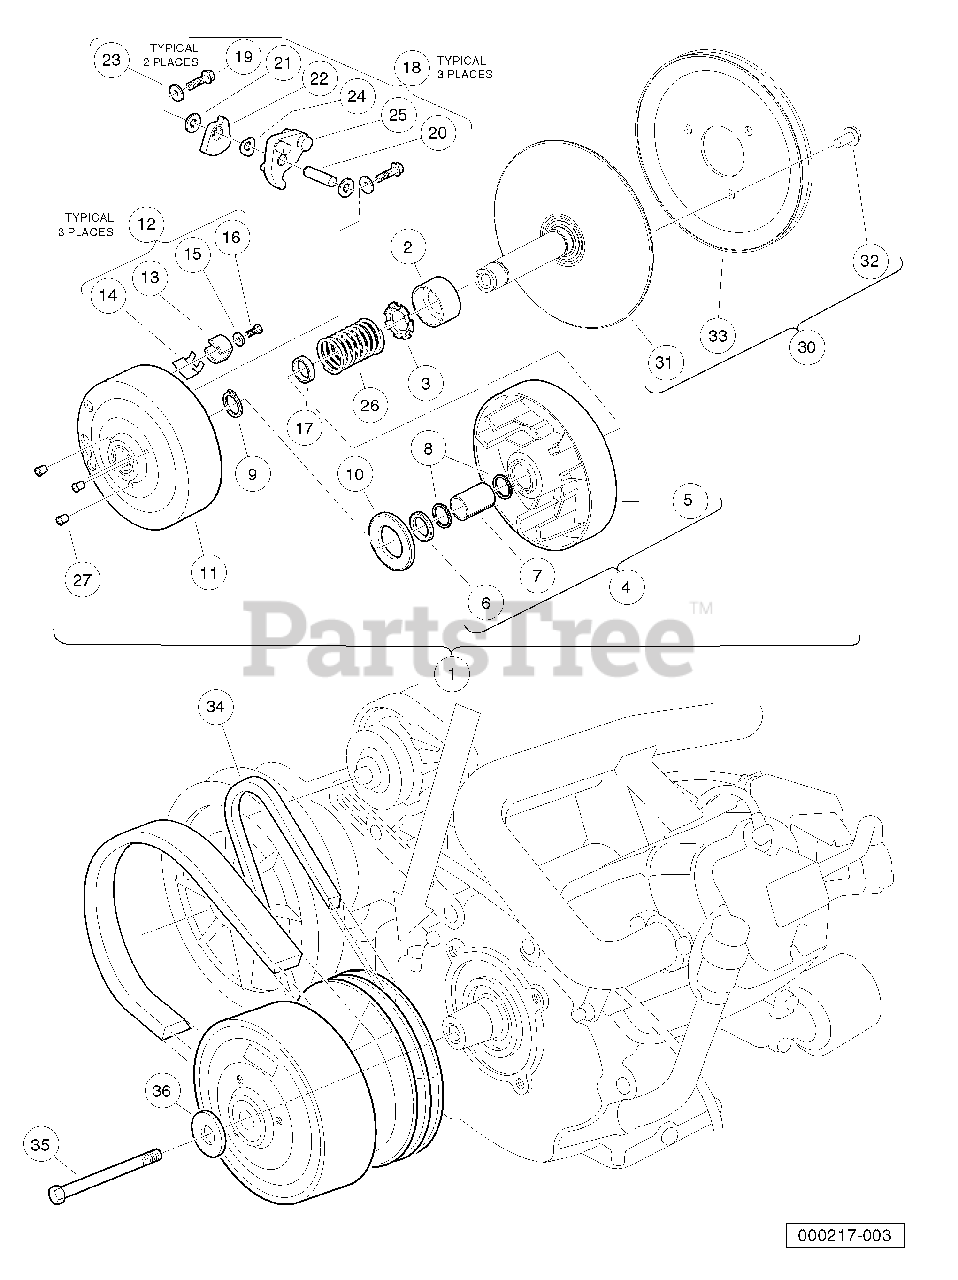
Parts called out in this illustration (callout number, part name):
1	Drive Clutch Assy. FE 350/272
2	Bearing, Idler
3	Retainer, Spring
4	Movable-Face Assembly
5	Drive Clutch Movable Face
7	Bushing, Split, Drive Clutch
8	Ring, Spiral Backup
9	Ring, 0.810" Internal Retaining
10	Washer, Thrust
11	Drive Hub Assy, Drive Clutch
12	Kit, Drive Clutch Button
13	Driver, Drive Clutch
14	Spring, Drive Button
15	Washer, #10 Type A Flat
16	Screw, #10-24 X 0.50 Hex-Head
17	Spacer, Fixed Face Shaft
18	Kit, Drive Clutch Weight
19	Screw, 1/4-20 X 1.00 Hex Head
20	Pin, 0.3752 X 1.50 Dowel
21	Washer, 0.38" ID Delrin Flat
22	Clutch Weight, Secondary
23	Washer
24	Washer, Wave
25	Weight, Primary
26	Spring, Drive Clutch
27	Cap Plug
28	Kit, Fxd Face Dr Asm Fe290/350
30	Assembly, Fixed-Face Drive
31	Fixed Face Assembly, Drive Clutch
32	Screw, 5/16-18 X 0.75 Thread-Forming
33	Pulley, Clutch
35	Screw 3/8-24x5.5 Hex Loc Ptch
36	Washer, 3/8 Type B Flat
